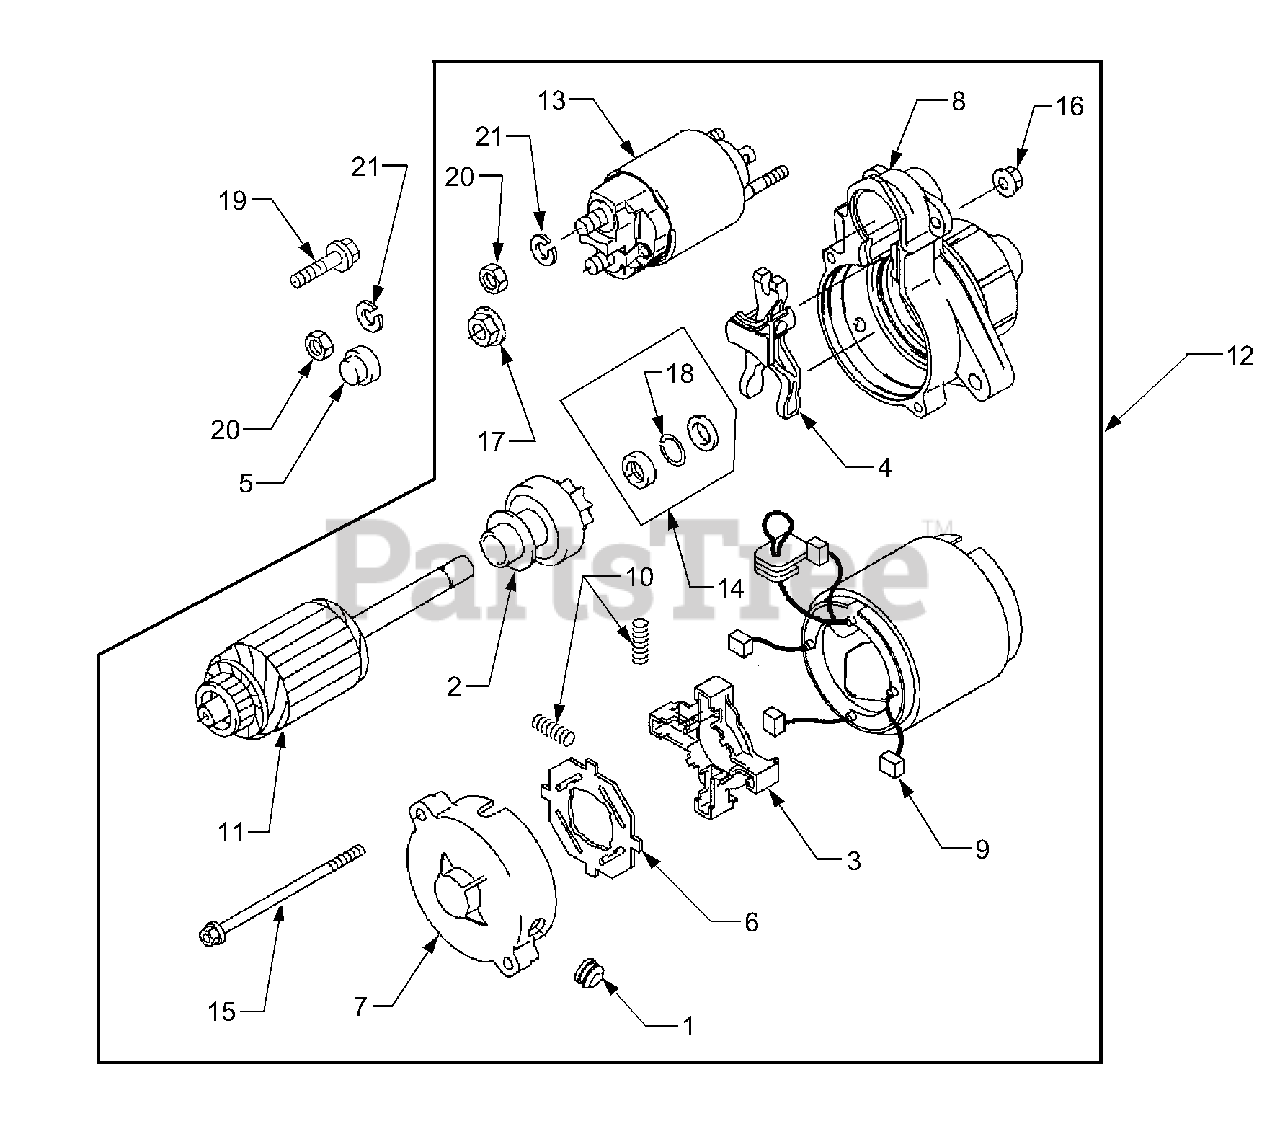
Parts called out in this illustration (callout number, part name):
2	Clutch Assembly
3	Holder, Brush
7	Cap, Starter End
8	Cone, Starter Nose
10	Spring, Brush
12	Starter, Electric
13	Solenoid, Starter
19	Bolt, Flanged
21	Washer, Spring
